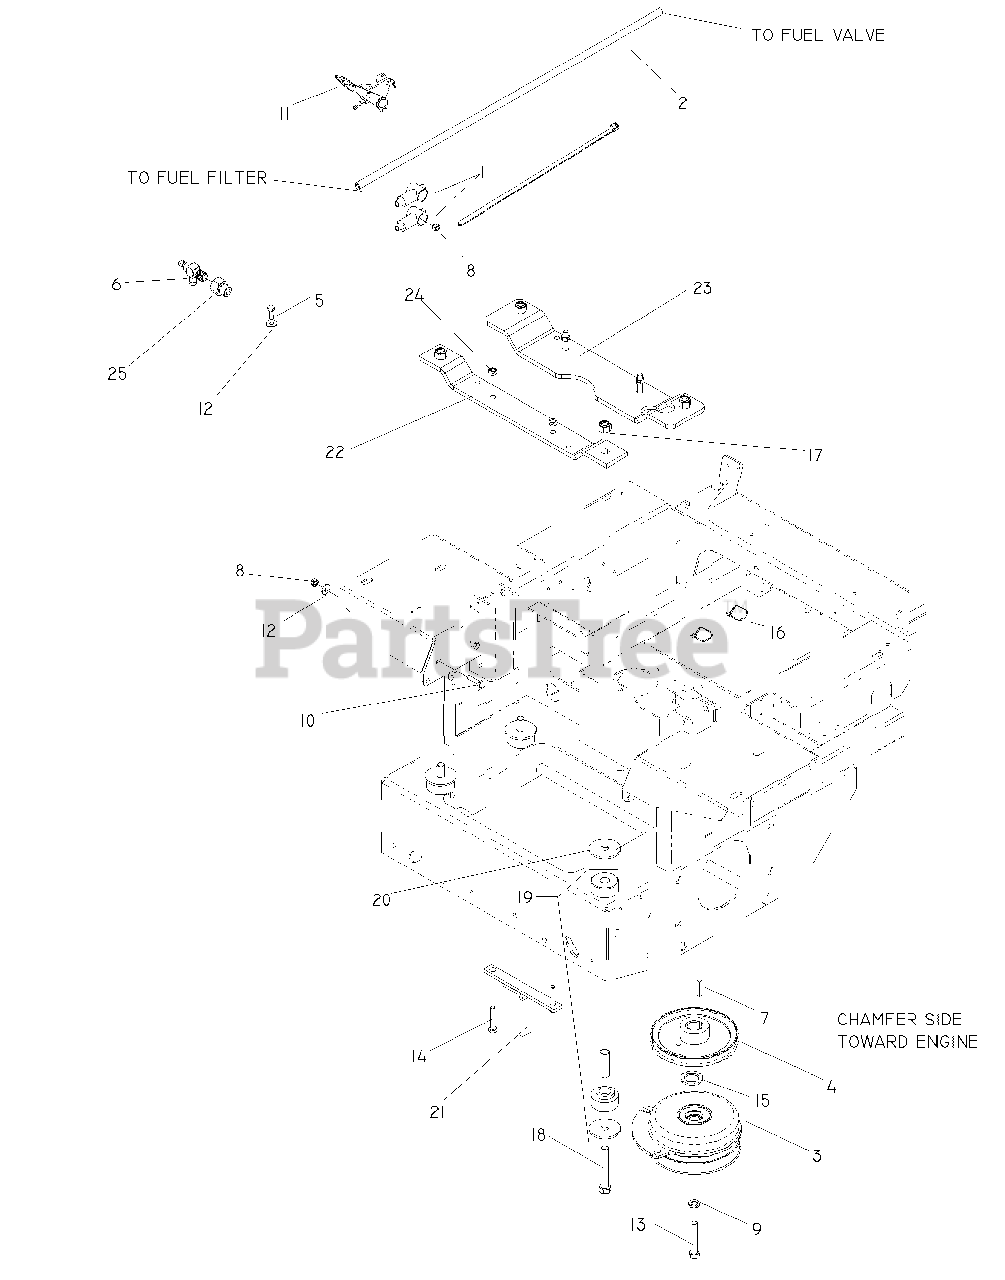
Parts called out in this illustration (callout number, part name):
1	INSULATOR
2	FUEL LINE 24"
3	CLUTCH-200 FT LB(RPLS 5218-102
5	HEX HEAD SCREW M6 X 1 X 20
6	OIL DRAIN ADAP.(HONDA)
7	KEY, 1/4 SQ X 1 1/4
8	NUT 1/4-20 NYLOC
9	WASHER 7/16 LOCK
10	HCS 1/4 X 1
11	CABLE CHOKE
12	WASHER 1/4 FLAT
13	BOLT 7/16F X 2 1/2
14	HCS 5/16C X 1 3/4
15	BUSHING, 10GA MACHINERY
16	TIE, PLASTIC
17	NUT 1/2-13 HEX NYLOC ZD
18	HCS 1/2C X 3 1/4
19	ISOLATORS
20	ISOLATOR WASHER
21	CLUTCH TIE DOWN
22	STRAP, ISO, REAR
23	MOUNT, ENGINE - BLACK
24	NUT 5/16C CENTERLOCK
